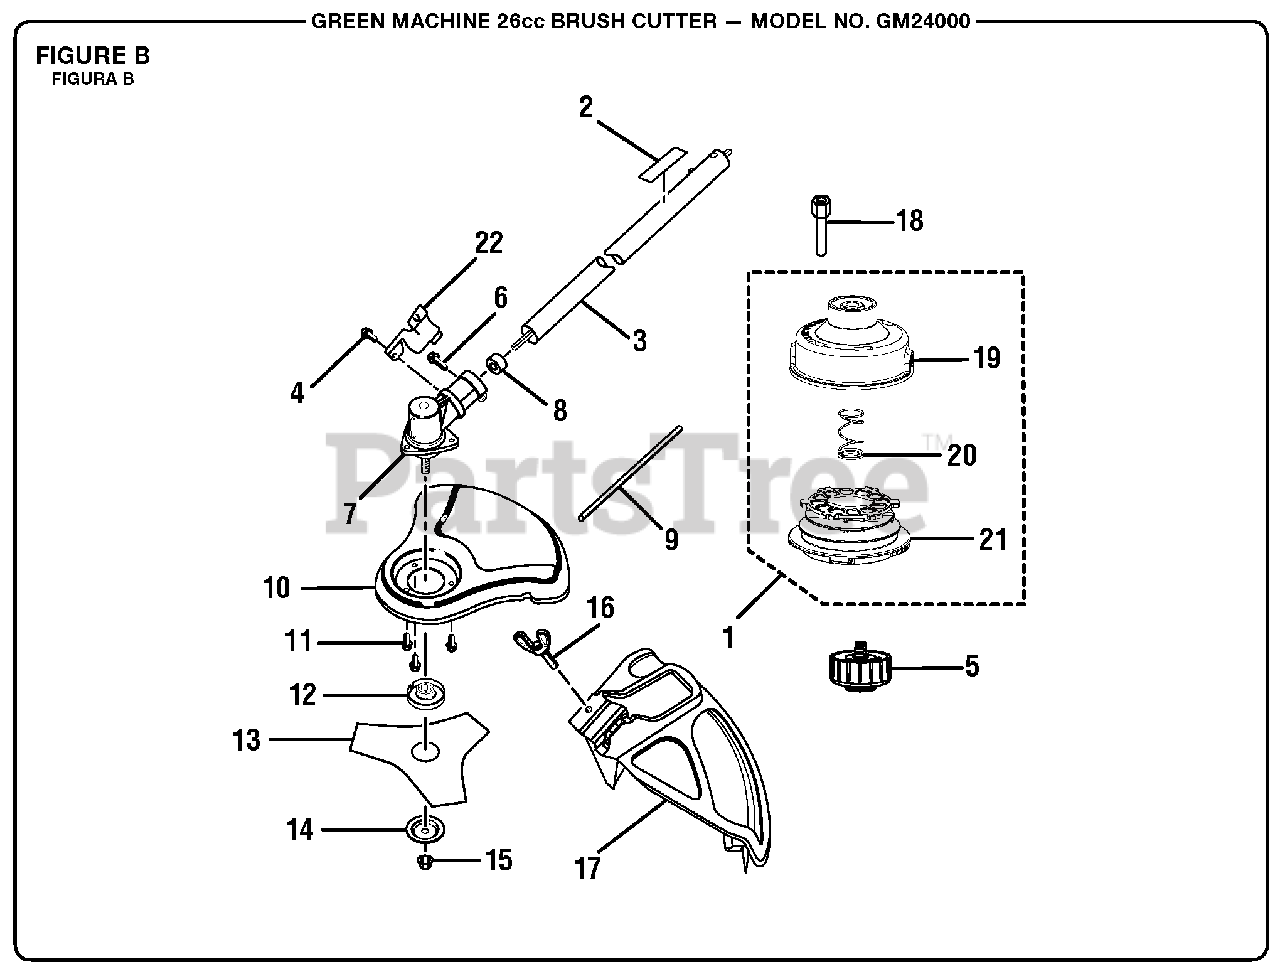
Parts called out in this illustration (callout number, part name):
1	String Head Assembly (Incl. Key Nos. 19-21)
2	Brushcutter Safety Label
3	Straight Shaft Assy
4	Screw (10-24 x 5/8 in.)
5	Spool Retainer
6	Screw (1/4-20 x 1-1/4 in.)
7	Gear Head
9	Gear Head Locking Tool
10	Brushcutter Guard
11	Screw (10-24 x 1/2 in.)
12	Flanged Washer
14	Cupped Washer
15	Blade Nut
16	Screw (1/4-20 x 1-1/4 in.)
17	Grass Deflector Assembly Incl. Key No. 16)
19	String Head Housing
20	Spring
21	Spool
22	Clamp
